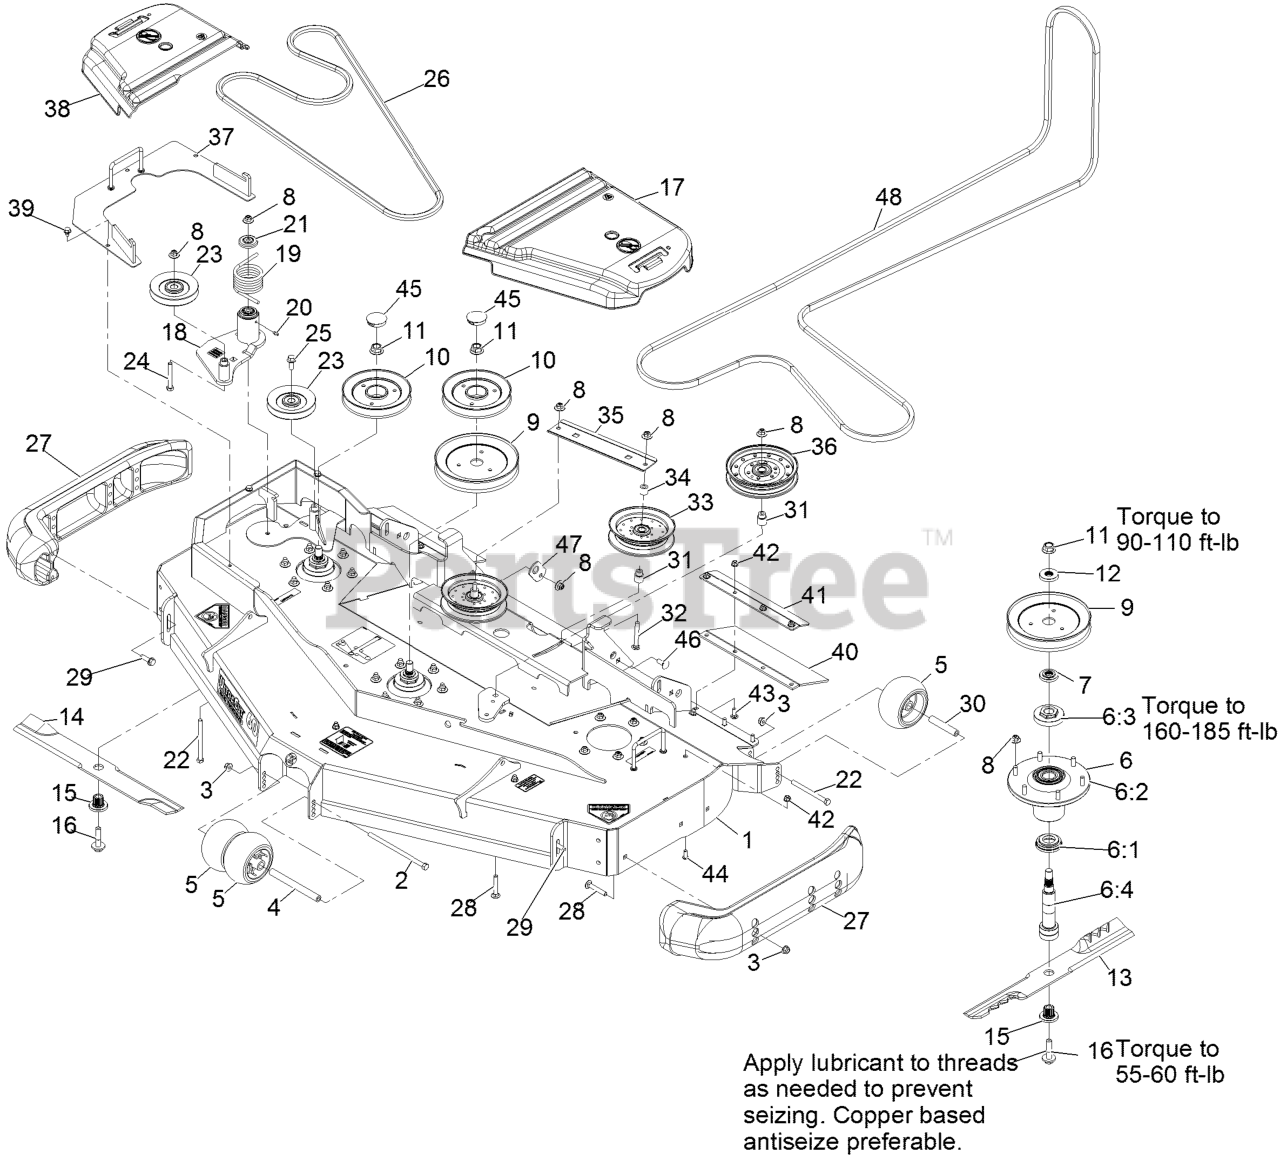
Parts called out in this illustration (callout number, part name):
1	DECK-RD60, W/DECALS
2	SCREW-HH
3	NUT-HF, NI
4	SPACER-WHEEL
5	ROLLER-SCALP, ANTI
6	ASM,SPINDLE HOUSING
6:1	GUARD,BOTTOM
6:2	ASM,CUTTER HOUSING
6:3	NUT, SPINDLE 7/8-14
6:4	SPINDLE,DOUBLE SPLINE
7	SPACER,SPLINED STEPPED
8	Nut-Nyloc 3/8-16 Flg
9	SHEAVE,BLADE DRIVE 7.25
10	SHEAVE-RD, REVERSE DRIVE
11	NUT-FLANGE, CENTERLOCK
12	SPACER,SPLINED
13	Blade-Extreme 2, 20.50"
14	Blade-Extreme 2-20.50, Rd60
14	Blade-Low Lift 20.5, Rd60
15	BUSHING,SPLINED
16	SCREW,SEMS 1/2-20 X 2.19
17	COVER-BELT, LH
18	ASM-DECK IDLER
19	SPRING-TORSION
20	FITTING-GREASE
21	GUARD-TOP
22	SCREW-HH
23	SHEAVE-4.14 A-SEC EOD
24	SCREW-HH
25	SCREW-HHF
26	BELT
27	SKID-BUMPER, DECK
28	Bolt-Carriage 3/8-16 X 2 1/4
29	SCREW-HWHTF
30	TUBE-SPANNER
31	BUSHING-IDLER
32	SCREW-CARR
35	GUIDE-RD BELT
37	COVER-DRIVE REVERSE
38	COVER-BELT, RH
40	GUARD-TIRE
41	SUPPORT-OUTER FLAP RD60
42	NUT-HF, NI
43	SCREW-CARR
44	SCREW-HSBH
45	PLUG,BLACK NYLON 1.75
46	BOLT-CARR
47	PLATE,DECK STRUT
48	BELT-V
